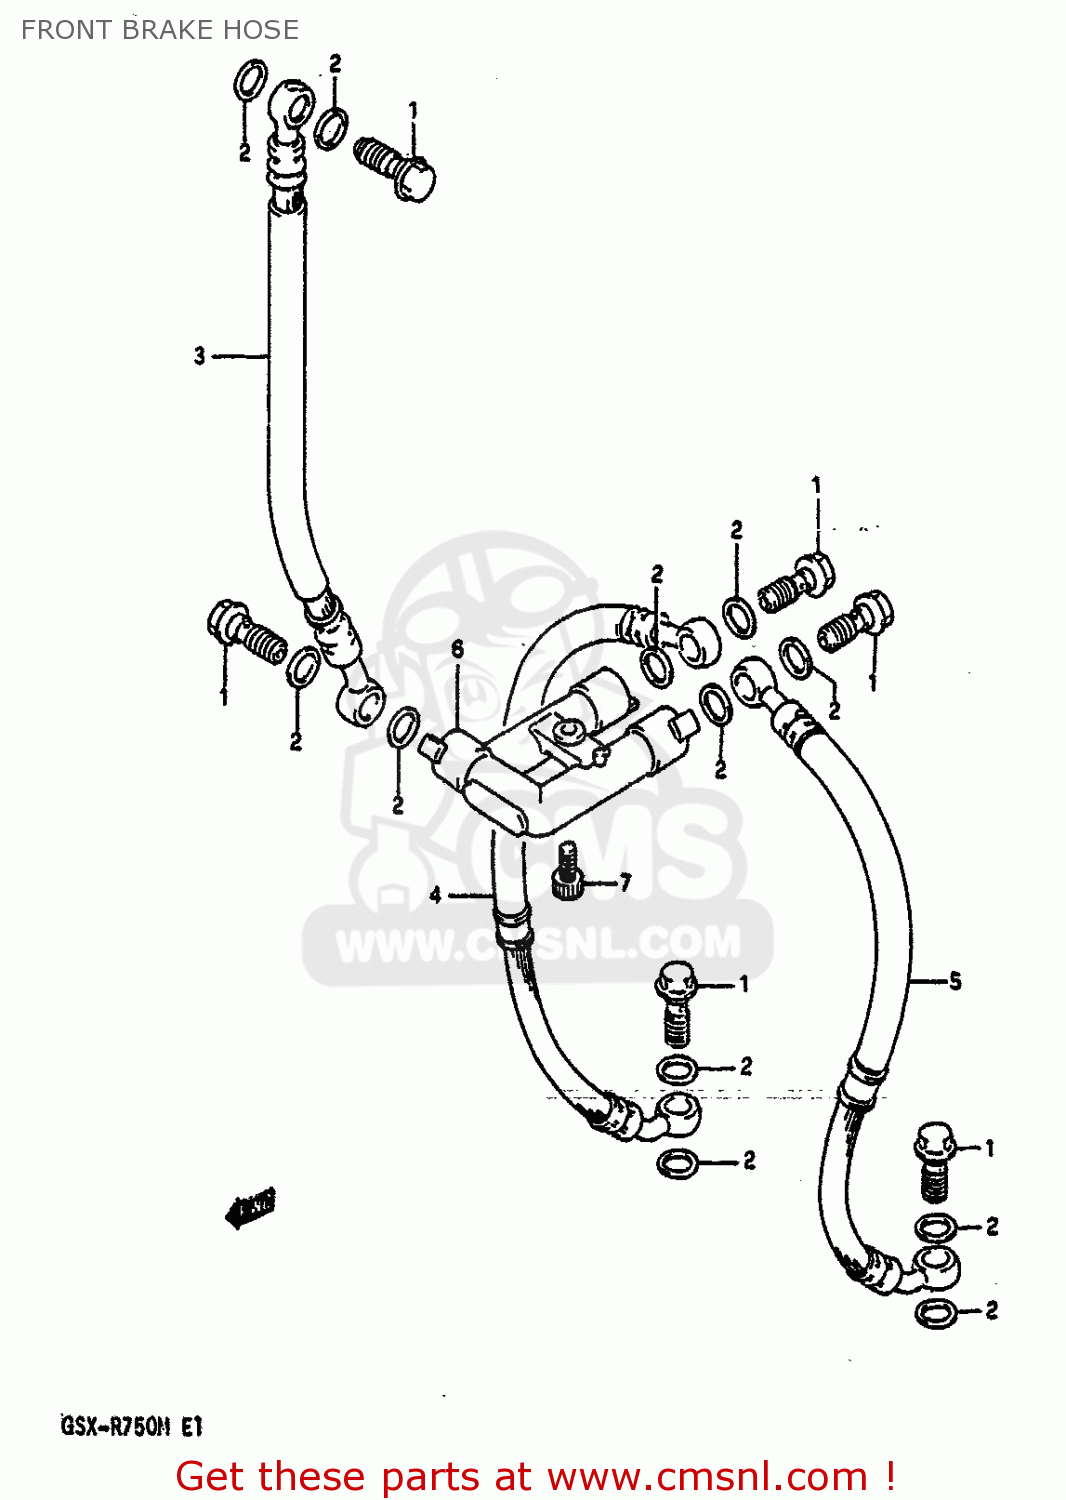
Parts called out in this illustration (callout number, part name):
1	BOLT UNION
2	WASHER(10X15X1.5)
3	HOSE COMP,FRONT BRAKE
4	HOSE COMP,FRONT BRAKE
5	HOSE,FR BRAKE NO.2,L
6	JOINT,BRAKE HOSE
7	BOLT
